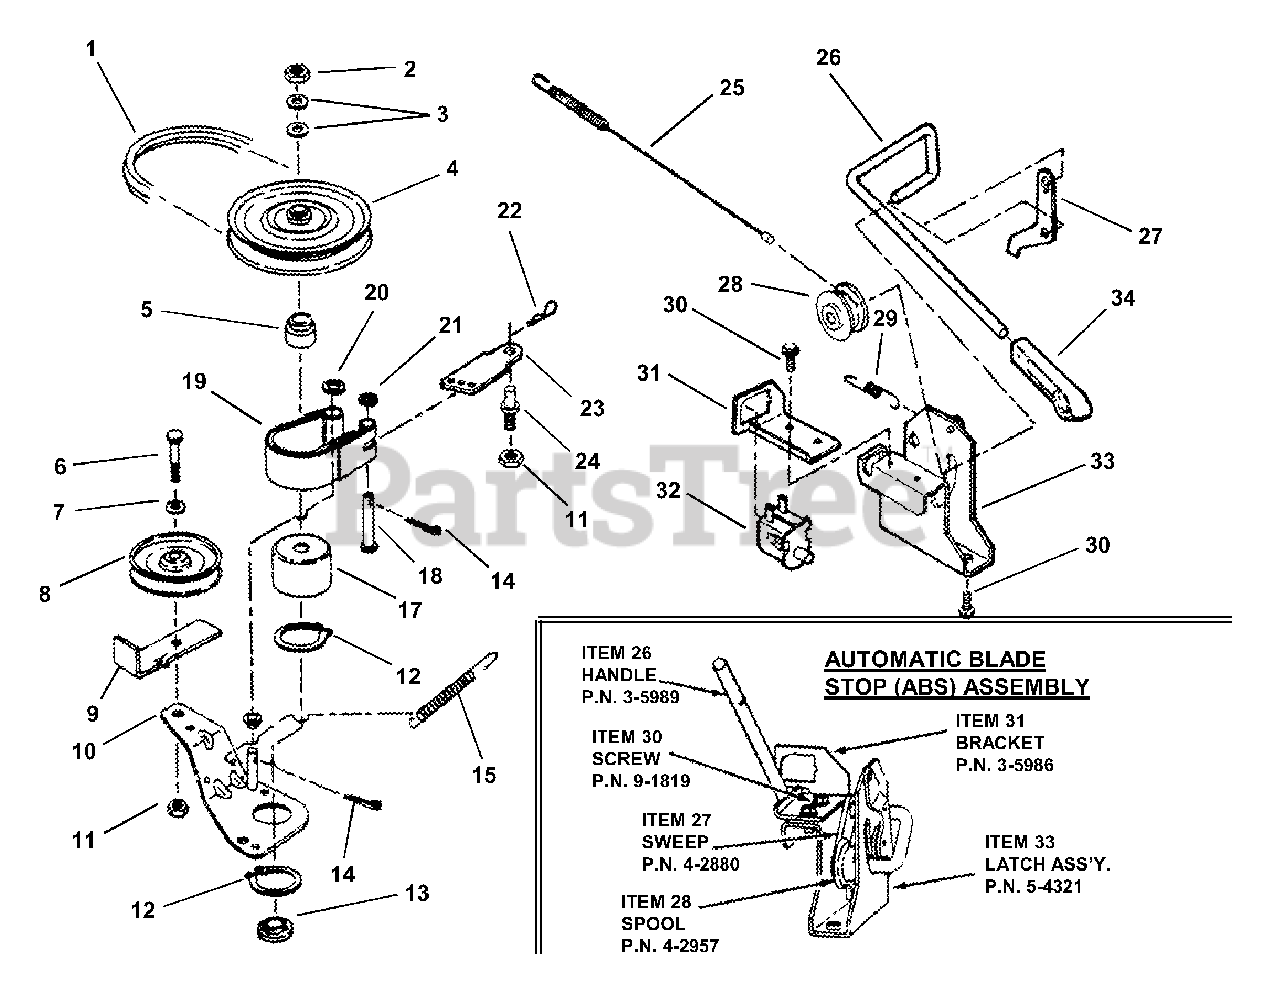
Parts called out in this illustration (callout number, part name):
1	BELT, Drive (72.25" AA Section)
2	NUT, 3/4-16 Hex Jam
3	WASHER, 49/64 x 1-1/2" Flat
4	PULLEY, Spindle
5	HUB, Pulley
6	SCREW, 3/8-24 x 1-3/4" Hex Head Cap, Grade 5
7	WASHER, 3/8" Flat
8	PULLEY, Idler
9	RESTRICTOR, Belt
10	ARM, Idler
11	NUT, 3/8-24 Hex Nyloc
12	RING, 2" External Retaining
13	WASHER, Spindle
14	PIN, 3/32 x 3/4" Cotter
15	SPRING
16	SPACER
17	DRUM, Brake
18	PIN, 1/4 x 1-5/8" Clevis
19	BAND, Brake
20	WASHER, 3/8" Flat
21	WASHER, 1/4" Flat
22	HAIRPIN, 5/64 x 1-3/16"
23	BRACKET, Brake Anchor
24	STUD (3/8-24 Thread)
25	CABLE & SPRING, Clutch Assembly
26	HANDLE, Blade Lever (ON-OFF)
27	SWEEP, ABS
28	SPOOL
29	SPRING, ABS Return Latch
30	SCREW, 1/4-20 x 5/8" Hex Washer Head Self-Tap
31	BRACKET, Interlock Switch
32	SWITCH, Deck Interlock
33	ASSEMBLY, Clutch Latch
34	GRIP, Handle
